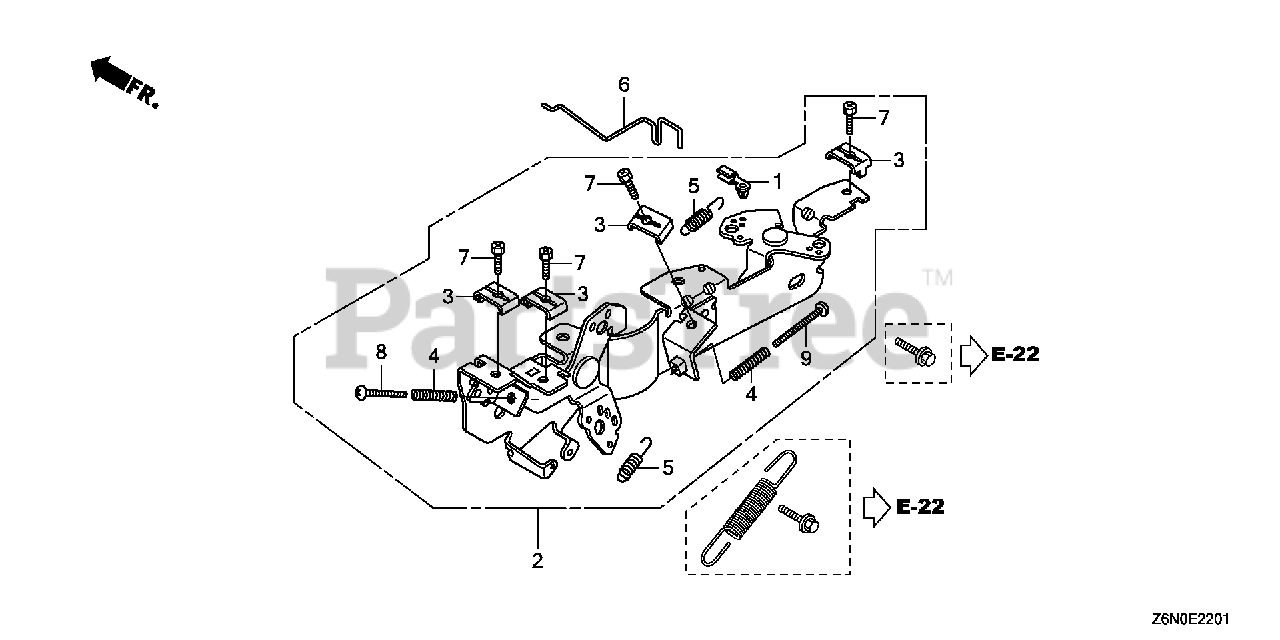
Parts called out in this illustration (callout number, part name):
1	JOINT, ROD
2	CONTROL ASSY.
3	HOLDER, CABLE
4	SPRING, CONTROL ADJUSTING
5	SPRING, CABLE RETURN
6	ROD, CHOKE CONTROL
7	BOLT, RECESSED (5X16)
8	SCREW, PAN (5X30)
9	SCREW, PAN (5X40)
